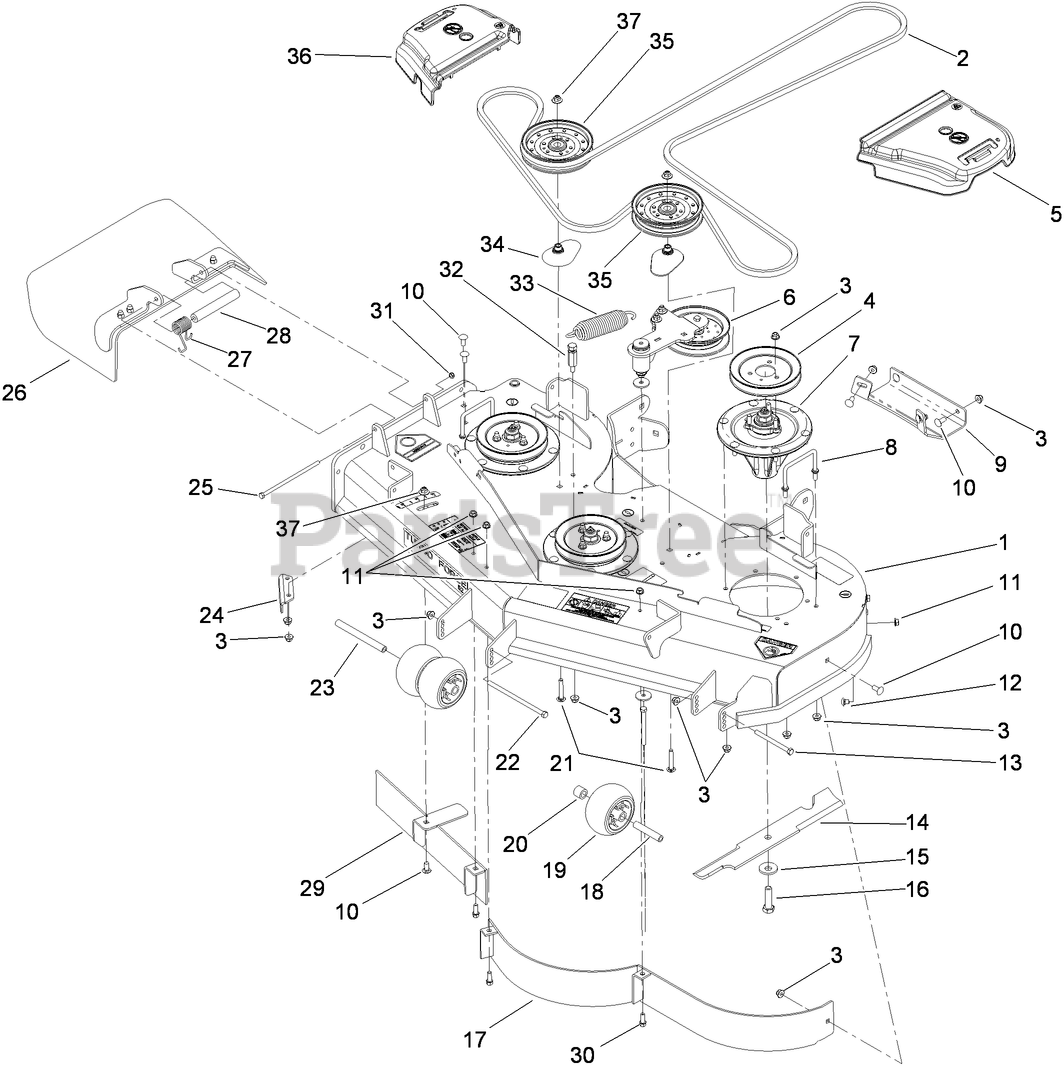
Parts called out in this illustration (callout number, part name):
1	DECK DECAL ASM
2	BELT-V
3	NUT-HF, NI
4	PULLEY
5	COVER-BELT, LH
6	IDLER ARM ASM
7	SPINDLE ASM
8	WIREFORM-COVER
9	PLATE-SKID
10	SCREW-CARR
11	NUT-HHF, WHIZ
12	SCREW-CARR
13	SCREW-HH
14	BLADE-18IN, HI FLOW
15	Washer-Blade Bolt, Heavy
16	SCREW-BLADE
17	BAFFLE ASM
18	TUBE-SPANNER
19	ROLLER-SCALP, ANTI
20	TUBE-SPACER
21	BOLT-CARR, SHORT NECK
22	SCREW-HH
23	SPACER-WHEEL
24	BAFFLE-DISCHARGE
25	SCREW-HH
26	RUBBER DEFLECTOR ASM
27	SPRING-TORSION
28	SPACER
29	BAFFLE ASM
30	SCREW-HWH
31	NUT-LOCK, NI
32	ANCHOR-SPRING, TALL
33	EXTENSION-SPRING
34	SPACER-PULLEY
35	PULLEY-IDLER, FLAT
36	COVER-BELT, RH
37	NUT-FLANGE, NI
